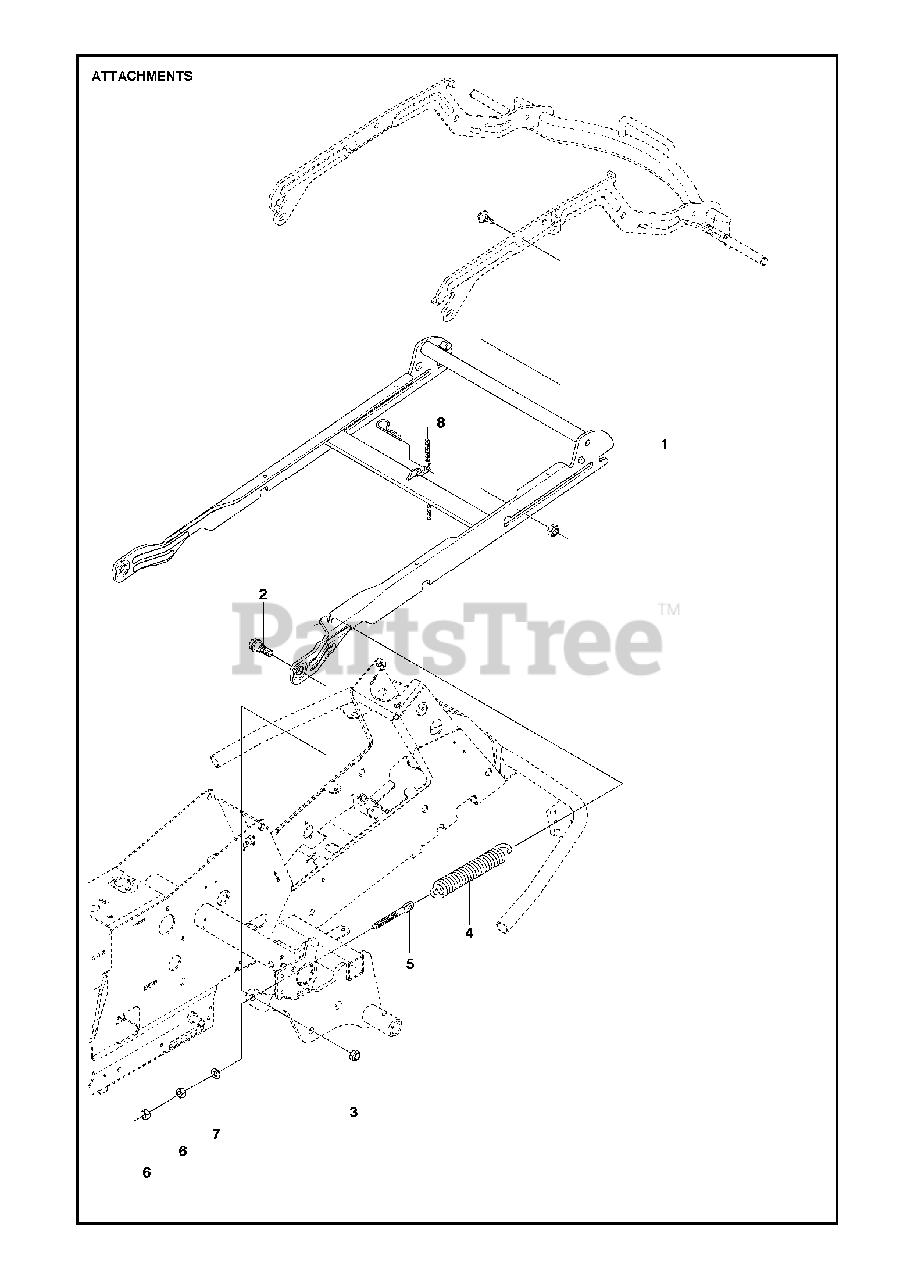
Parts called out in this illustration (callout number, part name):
3	Lock Nut, Fiber M12 DIN 985 Z/P
6	NUT
7	WASHER
